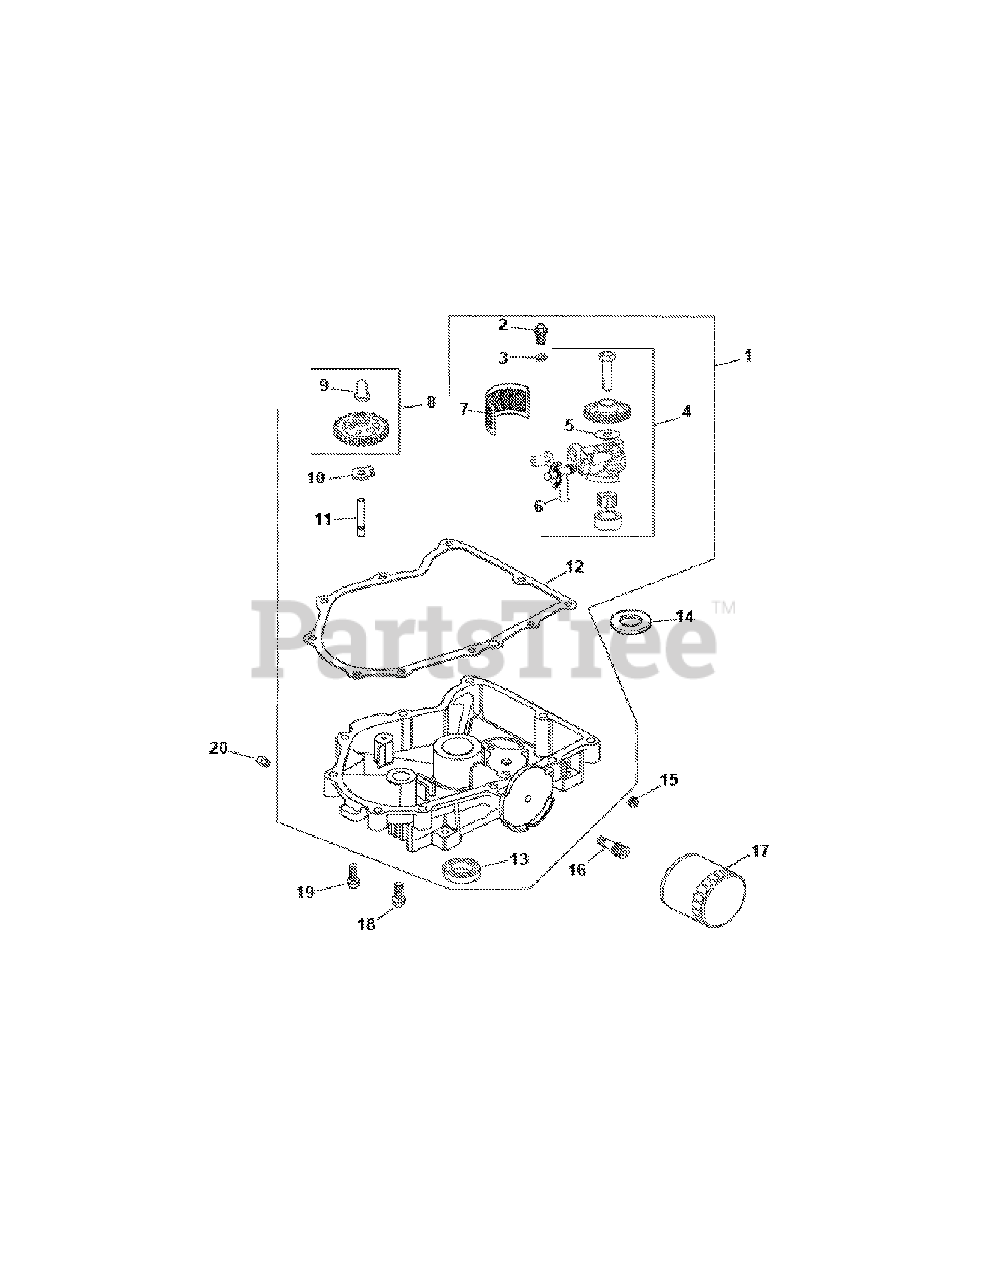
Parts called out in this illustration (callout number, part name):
1	Oil Pan w/Gasket Kit
2	Screw
4	Oil Pump Kit
6	Oil Pickup Tube
8	Governor Gear w/Pin Kit
11	Governor Gear Shaft
12	Oil Pan Gasket
13	Seal
16	Oil Filter Nipple
17	Oil Filter
18	Hex Flange Screw
19	Hex Flange Screw (M6 x 1.0 x 25)
